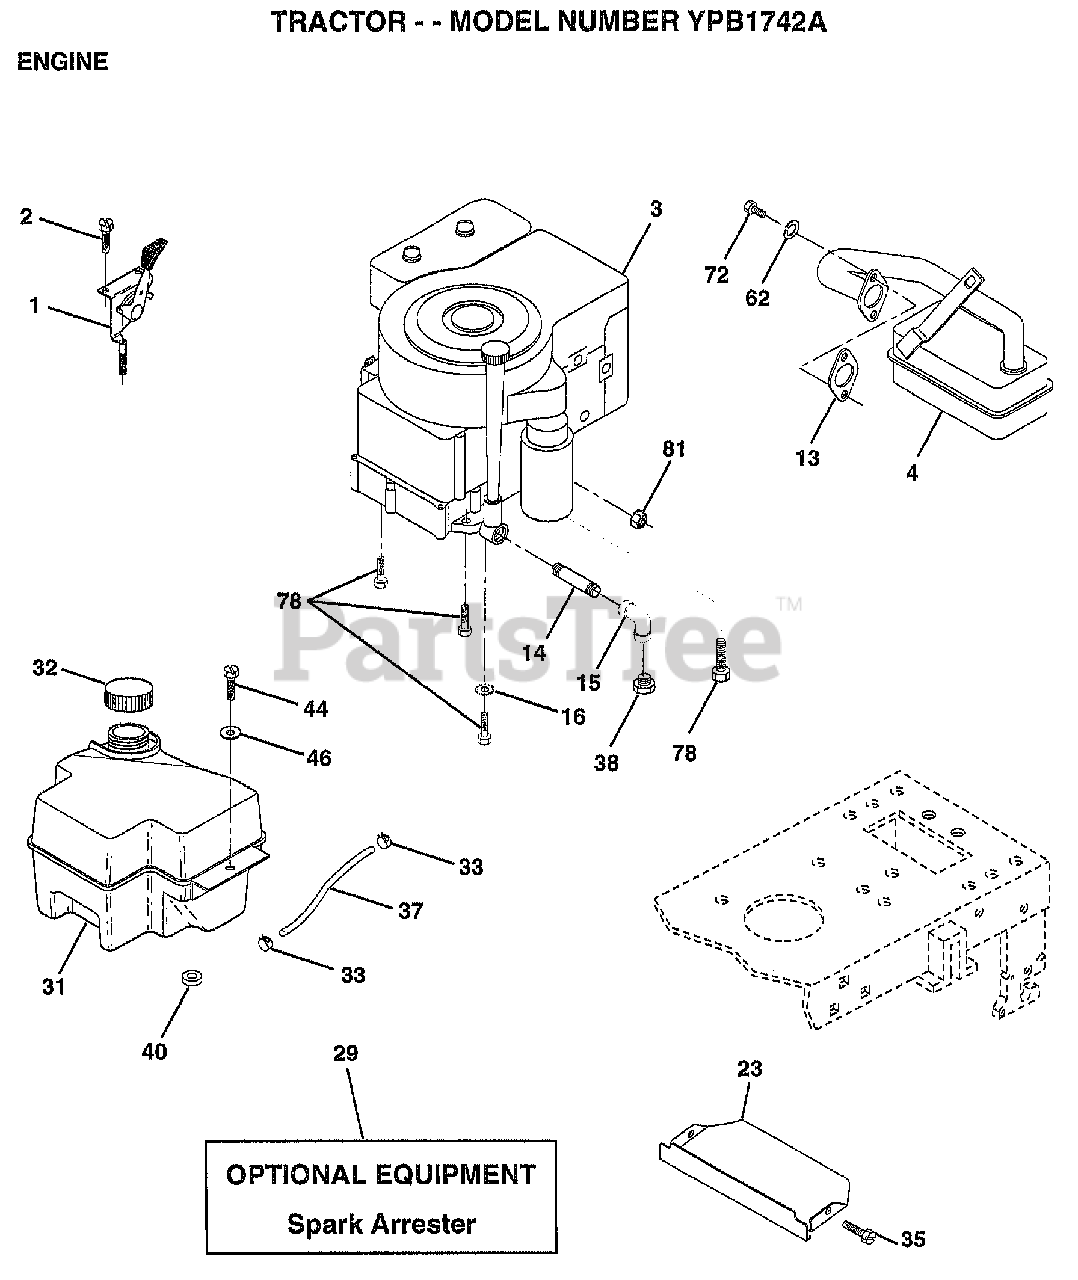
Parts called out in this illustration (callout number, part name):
1	CONTROL THROTTLE
2	SCREW LT
4	MUFFLER
14	PIPE NIPPLE
15	ELBOW
16	LOCKWASHER.5/16.E
23	SHIELD BRN/DBR GUARD
31	TANK.FUEL.FRONT.
32	CAP ASM FUEL
33	HOSE CLAMP
35	SCREW
37	LINE FUEL
44	SCREW HEX CRT
46	WASHER
62	LOCKWASHER
72	SCREW
78	SCREW
81	NUT
